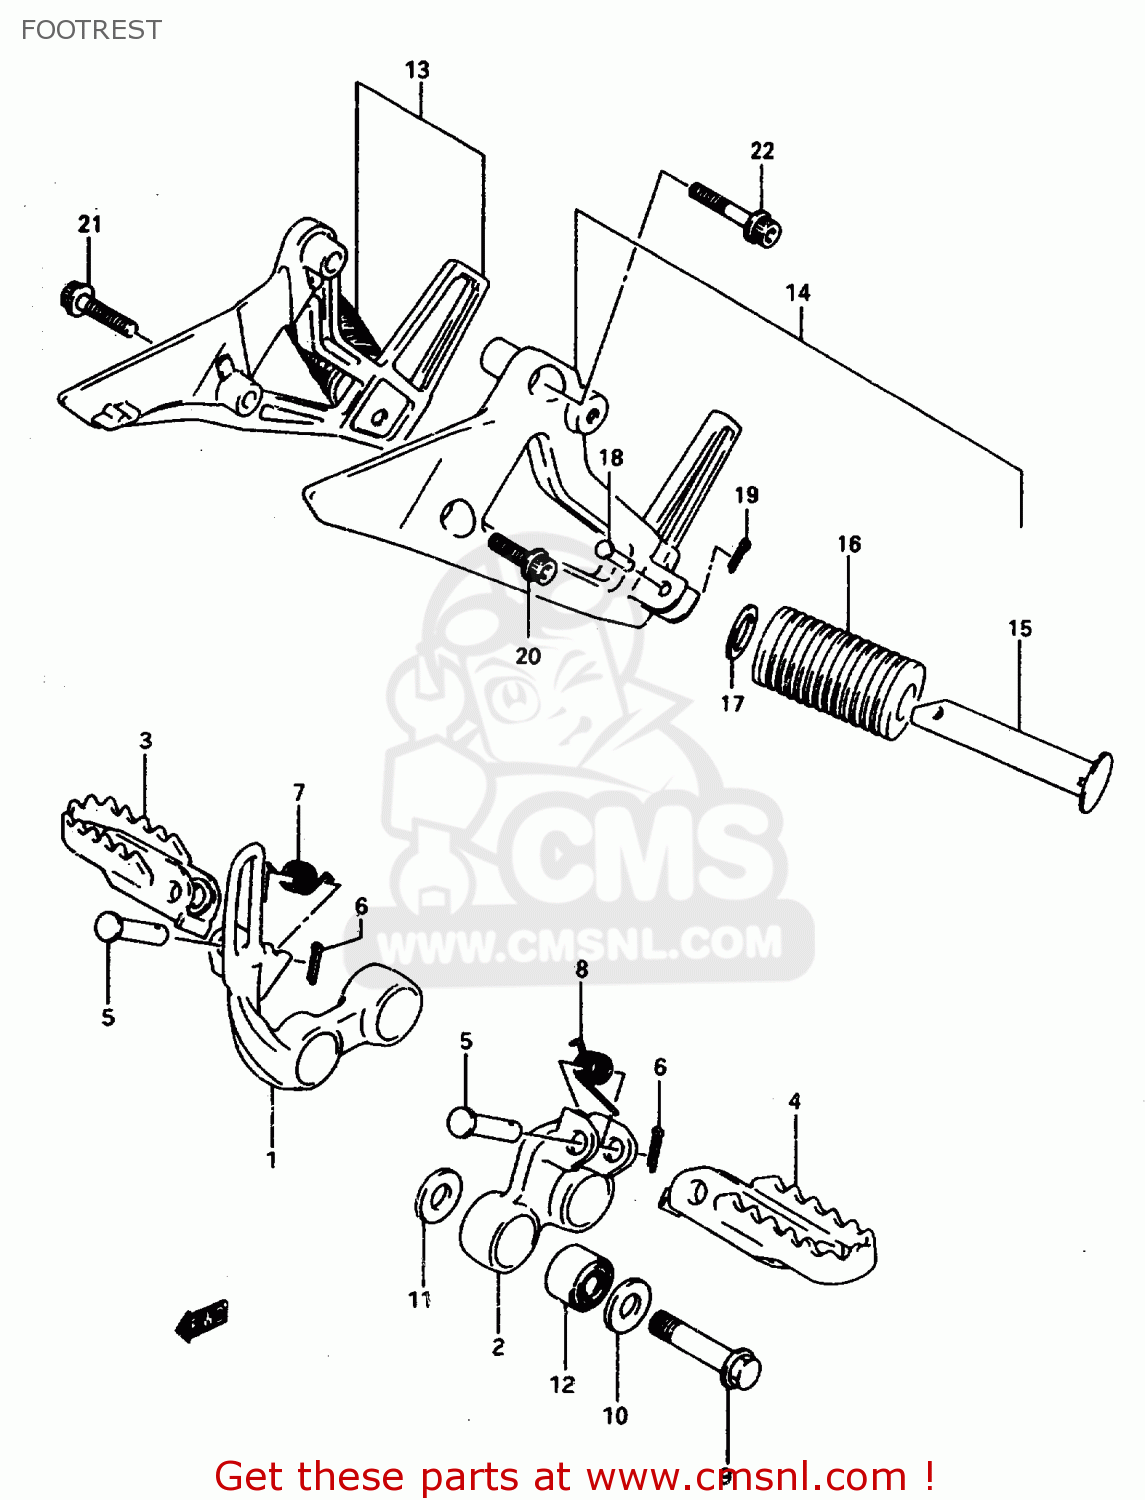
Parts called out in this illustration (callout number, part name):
1	BRACKET,FR FOOTREST,R
2	BAR, FOOTREST LH (BLACK)
3	FOOTREST,FR,R
4	FOOTREST,FR,L
5	PIN
6	PIN 20X20
7	SPRING
8	SPRING
9	BOLT(10X57)
10	WASHER (10.6X25X3.2)
11	WASHER
12	BUSH
13	FOOTREST ASSY,PILLION,R
14	FOOTREST ASSY,PILLION,L
15	BAR,PILLION FOOTREST
16	RUBBER,PILLION FOOTREST
17	WASHER (19.5X32X2)
18	PIN
19	PIN
20	BOLT
21	BOLT(8X30)
22	BOLT(8X40)
